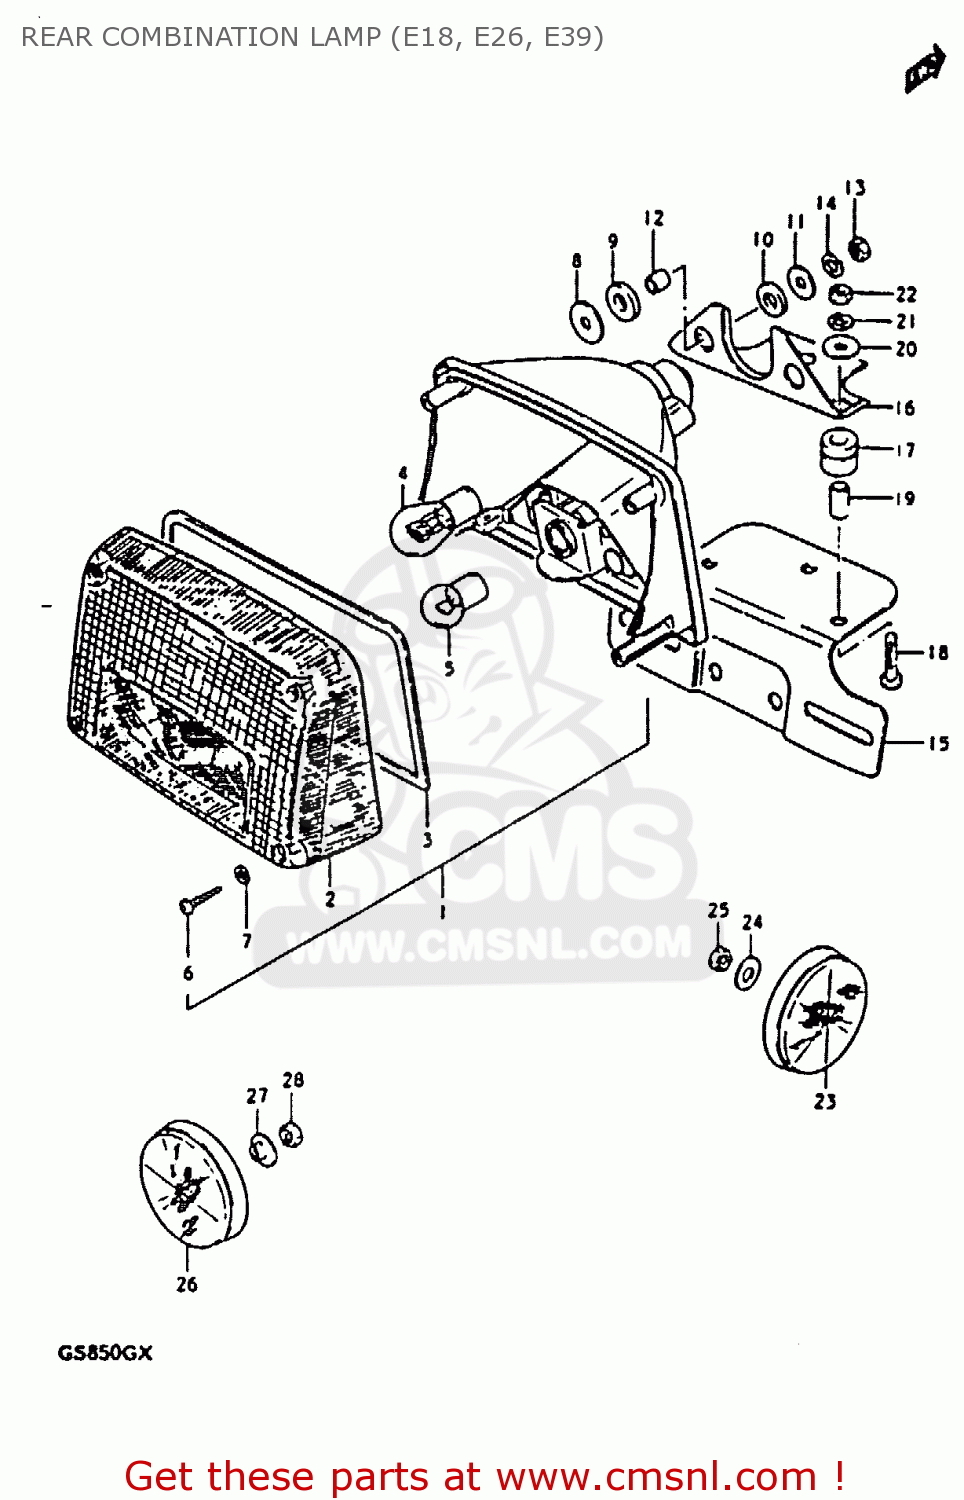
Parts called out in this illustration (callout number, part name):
1	LAMP, REAR COMBINATION
2	LENS
3	GASKET (NAS)
4	BULB 12V21/5W
5	BULB
6	BOLT
7	GASKET (NAS)
8	WASHER
9	CUSHION
10	CUSHION
11	WASHER(6,5X22X1.6)
12	SPACER(6.1X9X7.5)
13	NUT
14	LOCK WASHER
15	BRACKET, LICENCE PLATE
16	BRACKET,LICENSE PLATE
17	CUSHION, BRACKET
18	BOLT
19	SPACER (6.4X9X15.5)
20	WASHER
21	LOCK WASHER
22	NUT
23	REFLEX REFLECTOR,RR
24	WASHER
25	NUT
26	REFLEX REFLECTOR,RR
27	SPACER
28	NUT
